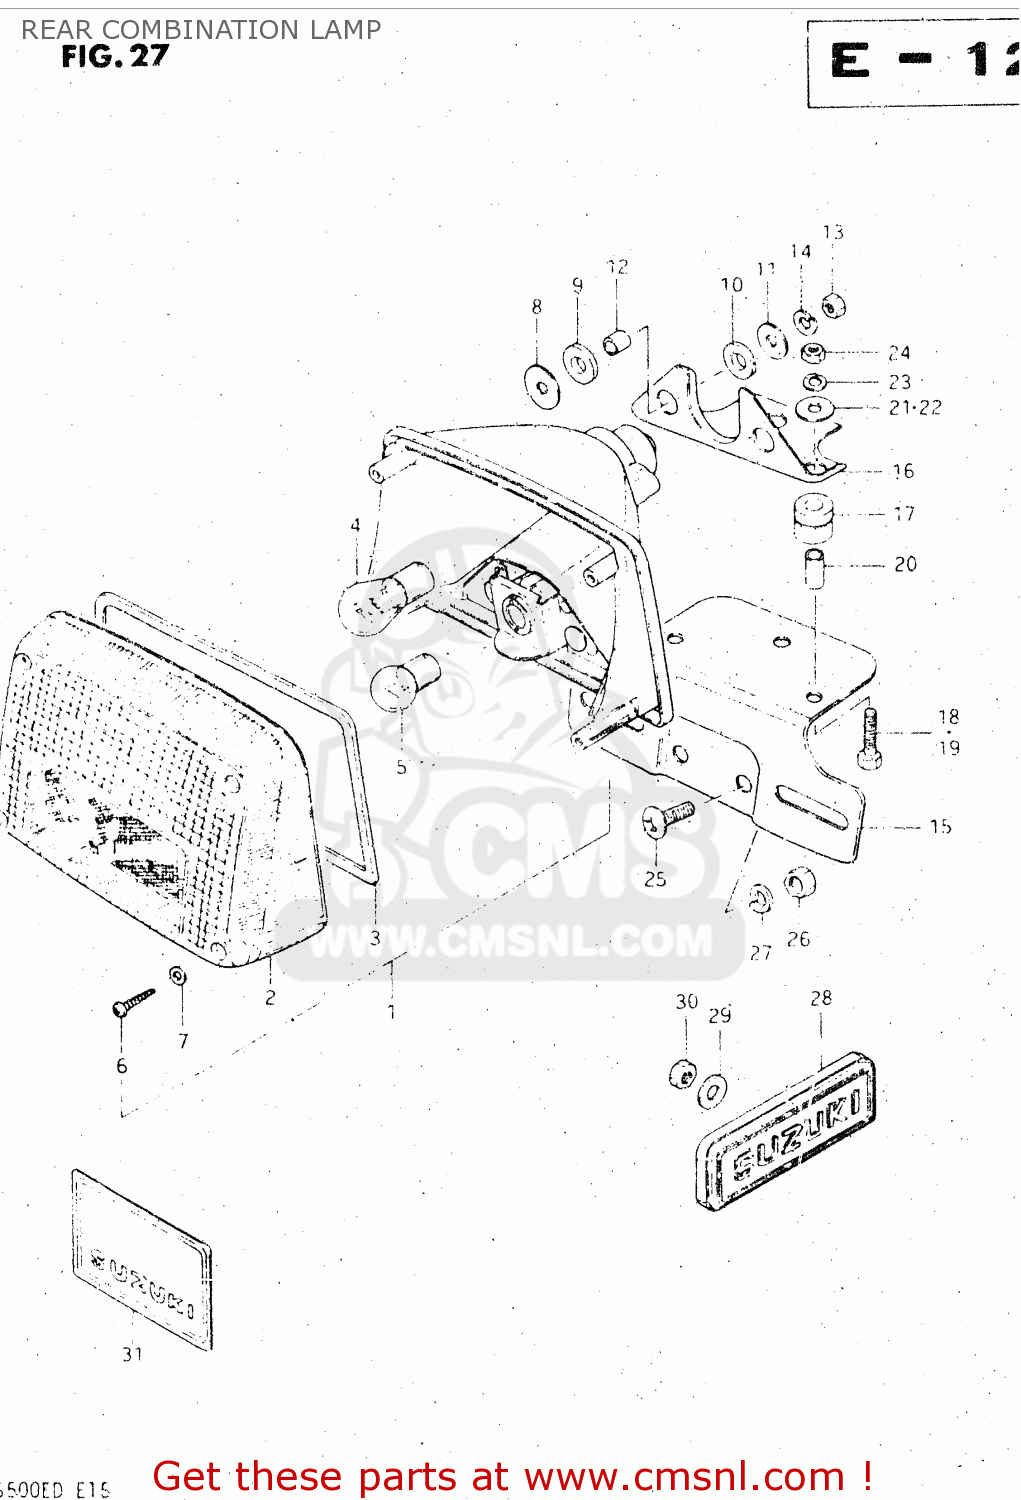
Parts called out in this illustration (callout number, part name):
1	LAMP ASSY, REAR COMBINATION
2	LENS,RR COMBI
3	GASKET
4	BULB(12V21/5W)
5	BULB
6	SCREW,REAR COMBINATION LAMP
7	GASKET (NAS)
8	WASHER
9	CUSHION
10	CUSHION
11	WASHER(6,5X22X1.6)
12	SPACER(6.1X9X7.5)
13	NUT
14	LOCK WASHER
15	BRACKET, LICENCE PLATE
16	BRACKET,LICENSE PLATE
17	CUSHION, BRACKET
18	BOLT
19	BOLT
20	SPACER (6.4X9X15.5)
21	WASHER
22	WASHER
23	LOCK WASHER
24	NUT
25	SCREW
26	NUT
27	LOCK WASHER
28	EMBLEM, REAR SIDE
29	WASHER
30	NUT
31	EMBLEM, REAR
